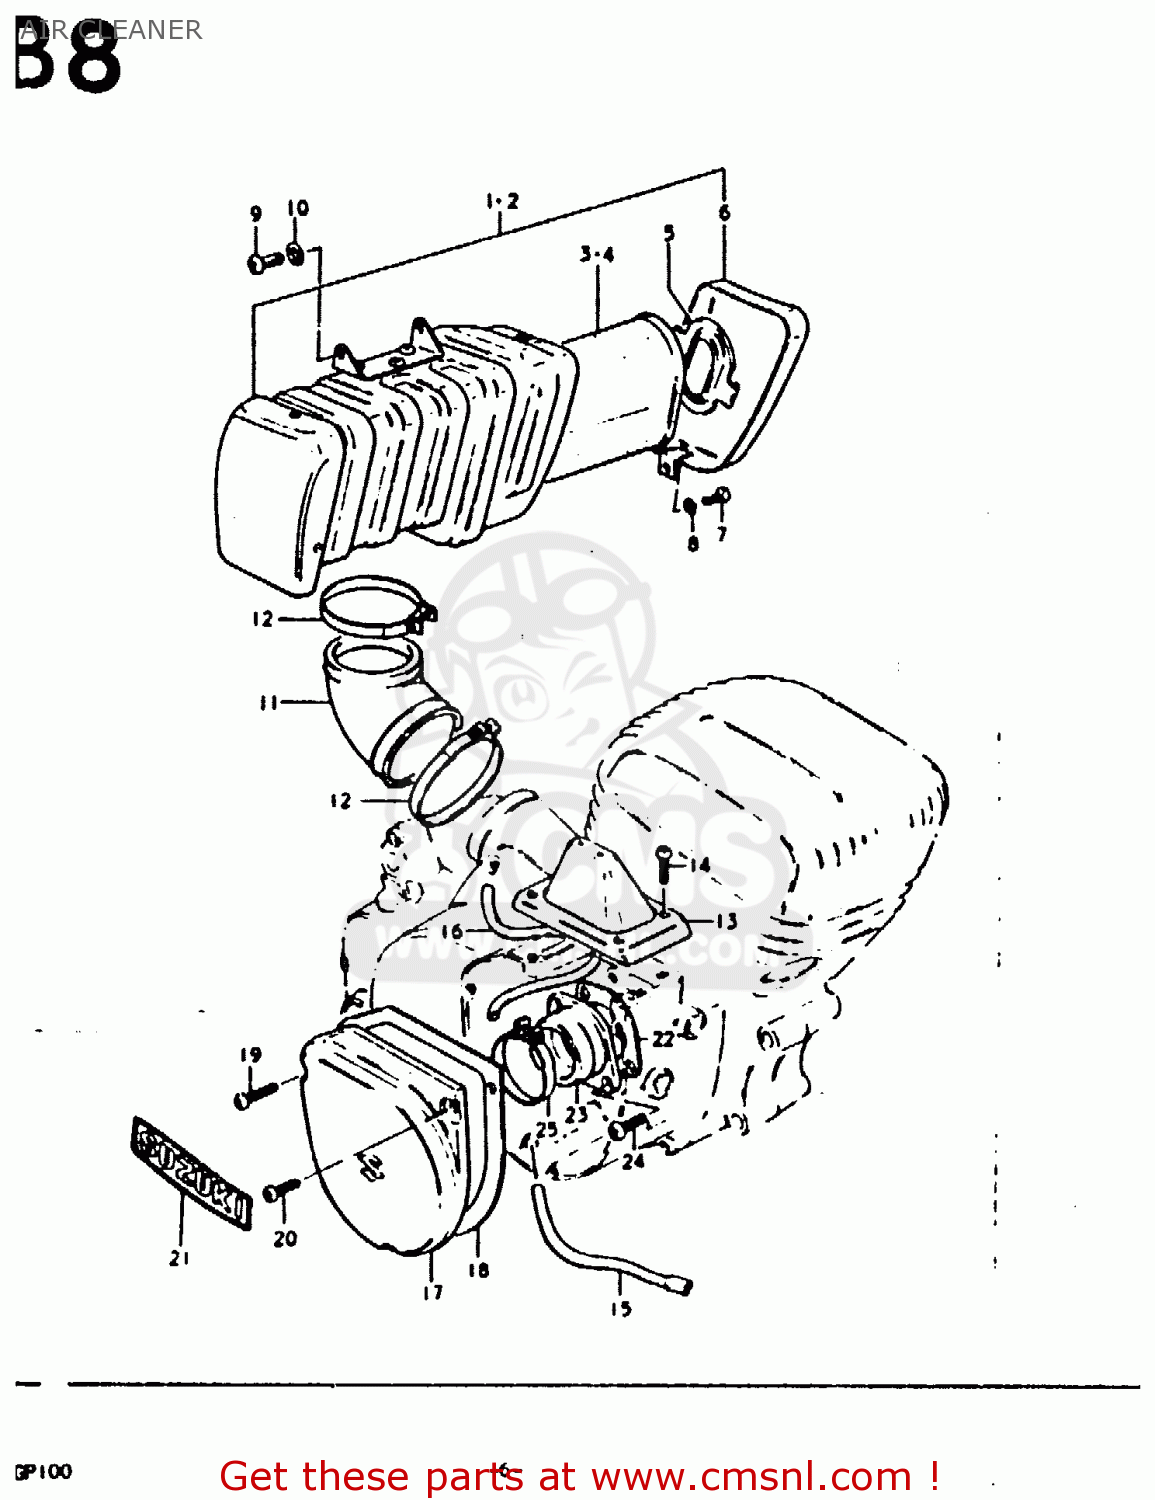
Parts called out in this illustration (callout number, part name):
2	CLEANER ASSY, AIR
3	FILTER ASSY,AIR CLEANER
4	FILTER
5	HOLDER
6	COVER
7	SCREW
8	LOCK WASHER
9	SCREW 6X12
10	WASHER
11	HOSE,CARBURETOR AIR INLET
12	CLAMP
13	CAP,CARBURETOR TOP
14	SCREW
15	HOSE,CARBURETOR AIR VENT
16	HOSE
17	CAP, CARB. INSPECTION
18	GASKET, CAP (MCA)
19	SCREW 5X20
20	SCREW
21	EMBLEM
22	GASKET,CARBURETOR (NAS)
23	PIPE,INTAKE
24	SCREW
25	CLAMP
